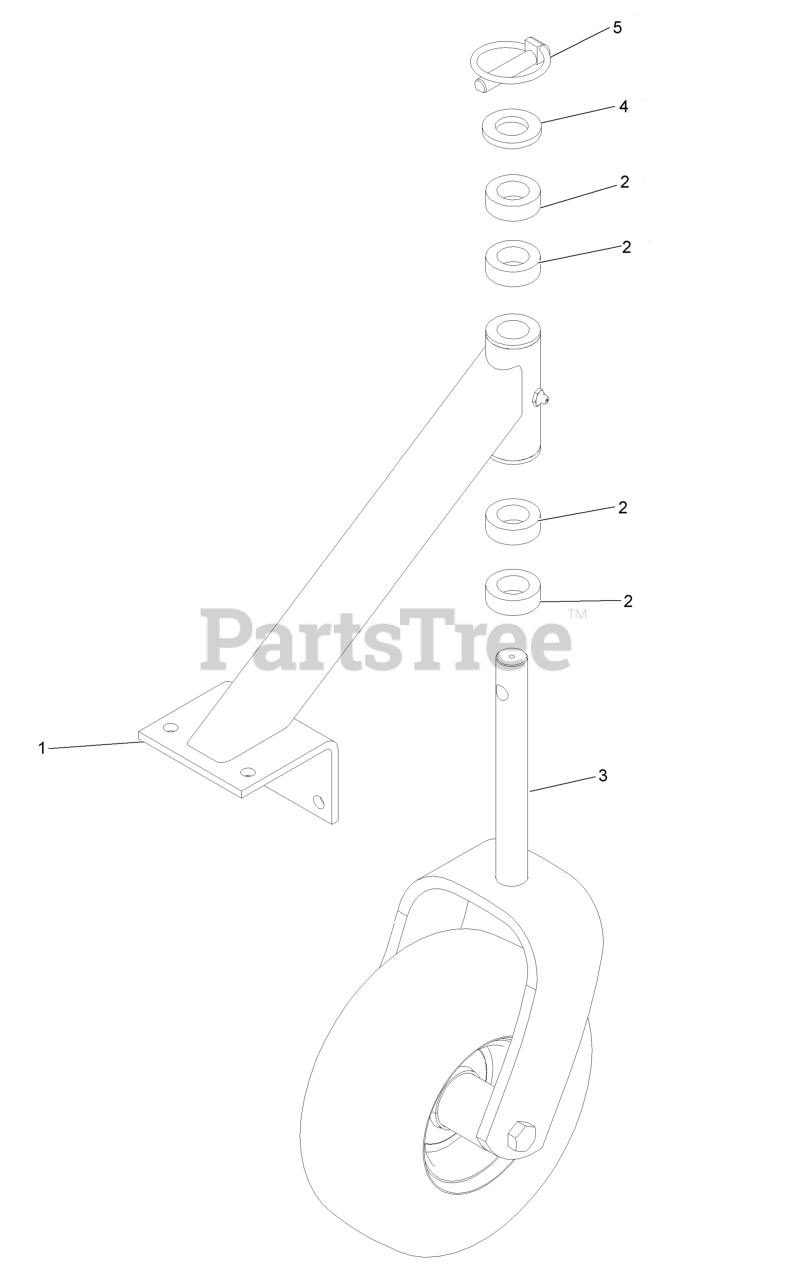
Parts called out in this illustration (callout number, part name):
1	SUPPORT ASM
2	SPACER-CASTER
3	ASM,CASTER/WHEEL
4	WASHER-FLAT
